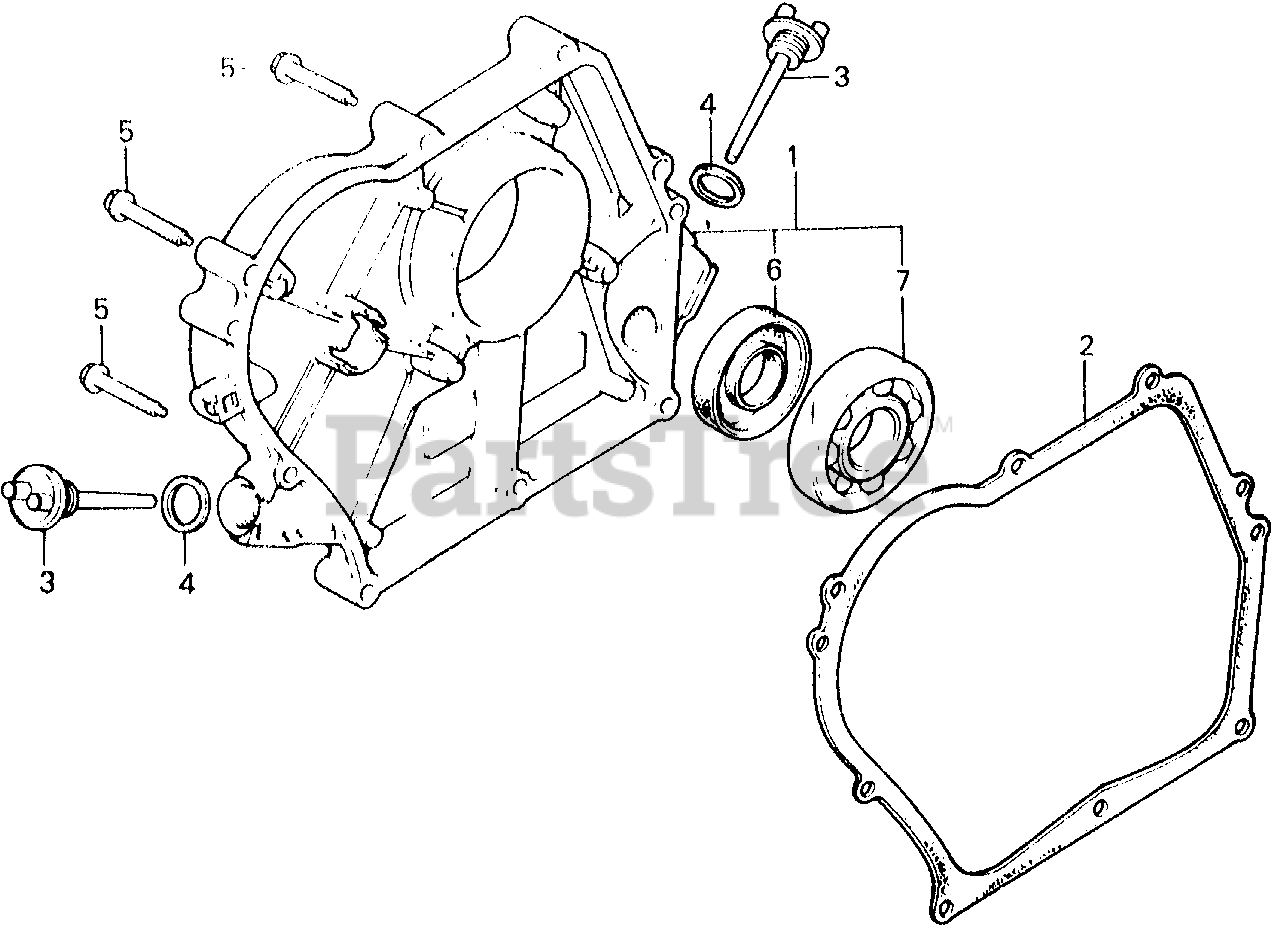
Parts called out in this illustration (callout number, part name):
1	COVER ASSY., CRANKCASE (S-TYPE)
1	COVER ASSY., CRANKCASE (HQ-TYPE)
2	GASKET, COVER
4	GASKET, OIL FILLER CAP
5	BOLT, FLANGE (6X32)
6	OIL SEAL (25X41X6)
7	BEARING, RADIAL BALL (6205)
